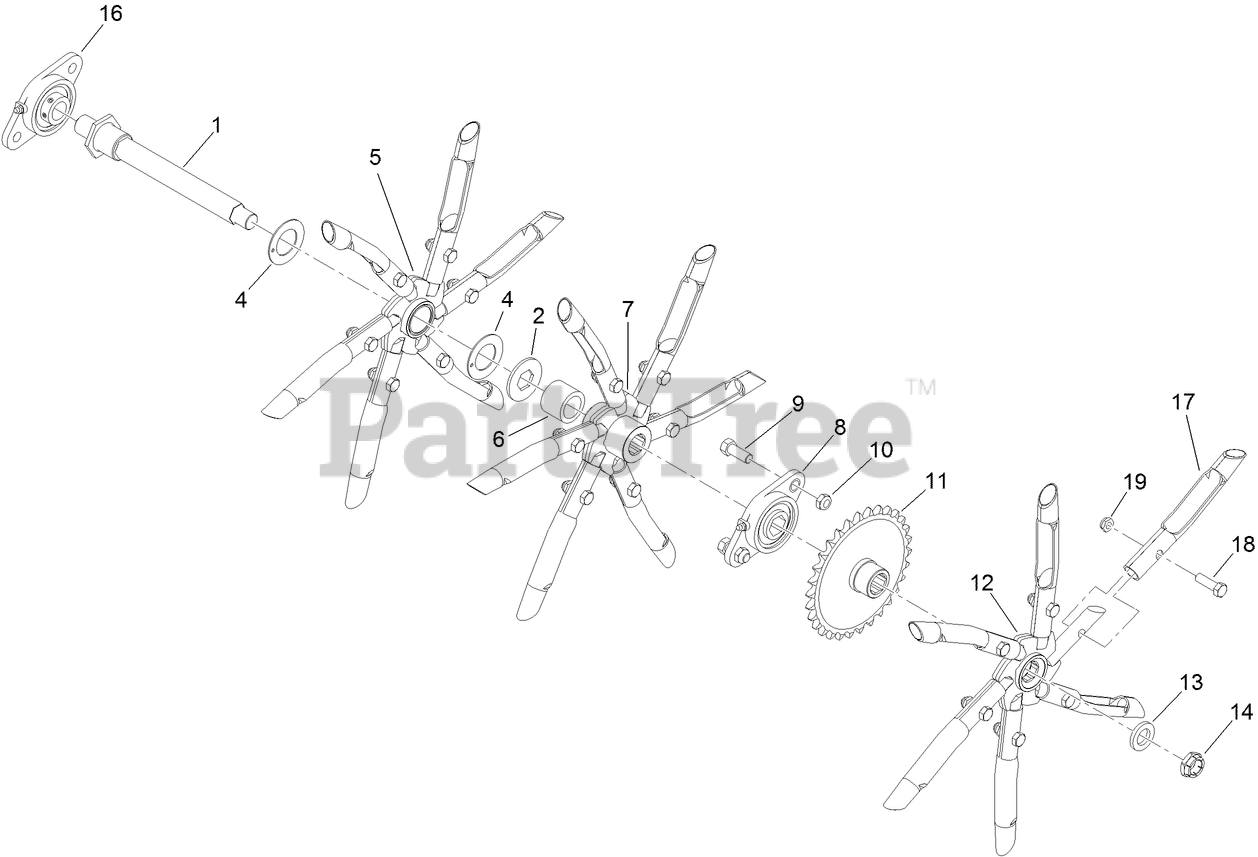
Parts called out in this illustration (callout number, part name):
1	TINE SHAFT ASM
2	KEEPER-TINE, FLOATING
4	WASHER-THRUST
5	FLOATING SPYDER ASM
6	SPACER-TINE
7	DRIVEN SPYDER ASM
8	BEARING-HEX BORE
9	SCREW-HH
10	NUT-LOCK
11	SPROCKET ASM
12	DRIVEN SPYDER ASM
13	WASHER-SPACER
14	NUT-LOCK
16	BEARING-ROUND BORE
17	TINE-CORING (3/4 INCH)
18	SCREW-HH
